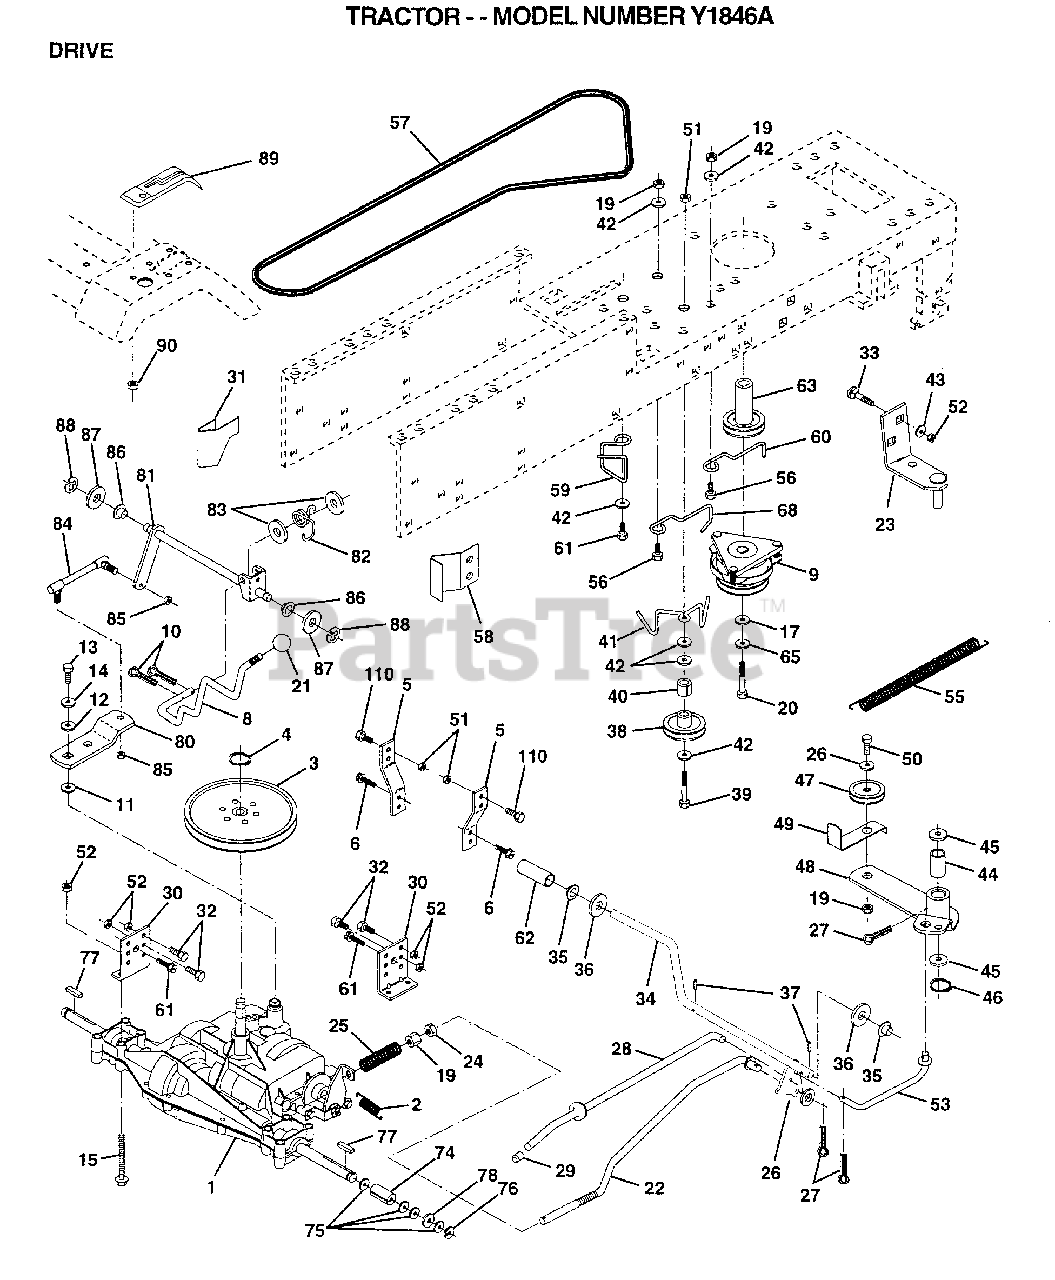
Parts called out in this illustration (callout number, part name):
1	ST WHL INSERT CAP
2	LOCKWASHER
3	WASHER T
5	SLEEVE STEERING
8	SHAFT.STEERING.LR
9	STEERING CLIP
10	BUSHING STEER LWR
11	RING
12	WASHER LT
13	ADAPTER LT
14	EXT SHAFT STEERIN
15	BOLT
16	NUT
17	BOLT
